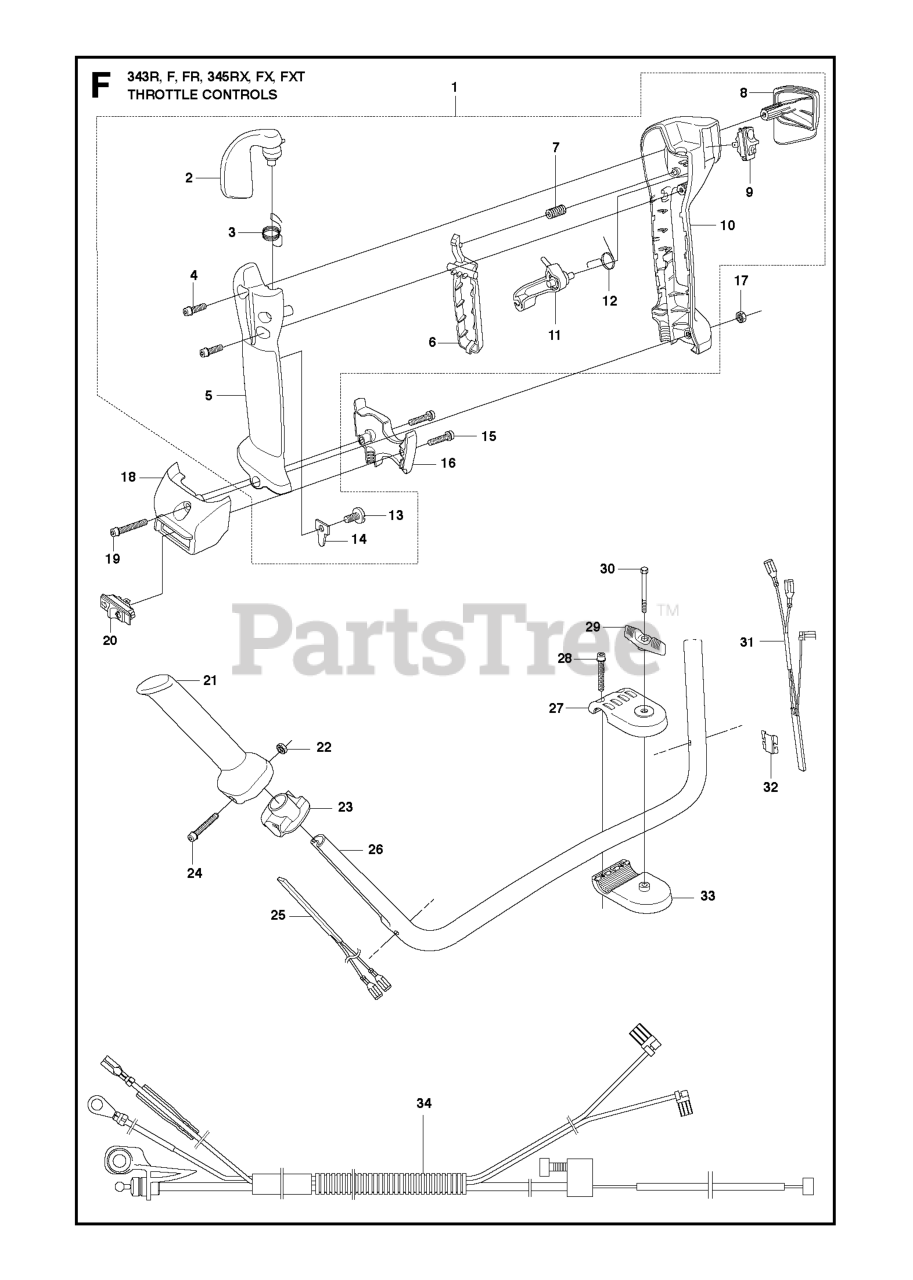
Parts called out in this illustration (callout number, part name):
1	THROTTLE HANDLE
2	THROTTLE TRIGGER
3	RP SPRING
5	HANDLE
6	THROTTLE LOCK
9	STOP BUTTON
10	HANDLE
15	SCREW
16	HOLDER
17	NUT M6M M5
18	HOLDER
19	SCREW
20	SWITCH (G)
21	HANDLE
22	NUT M6M M5
25	HEATING ELEMENT
26	RP HANDLE
26	%HANDLE
27	HANDLE HOLDER UPPER
30	%SCREW
31	HEATING ELEMENT
32	HOLDER
33	HANDLE HOLDER LOWER
34	WIRING ASSY
34	RP WIRING ASSY
